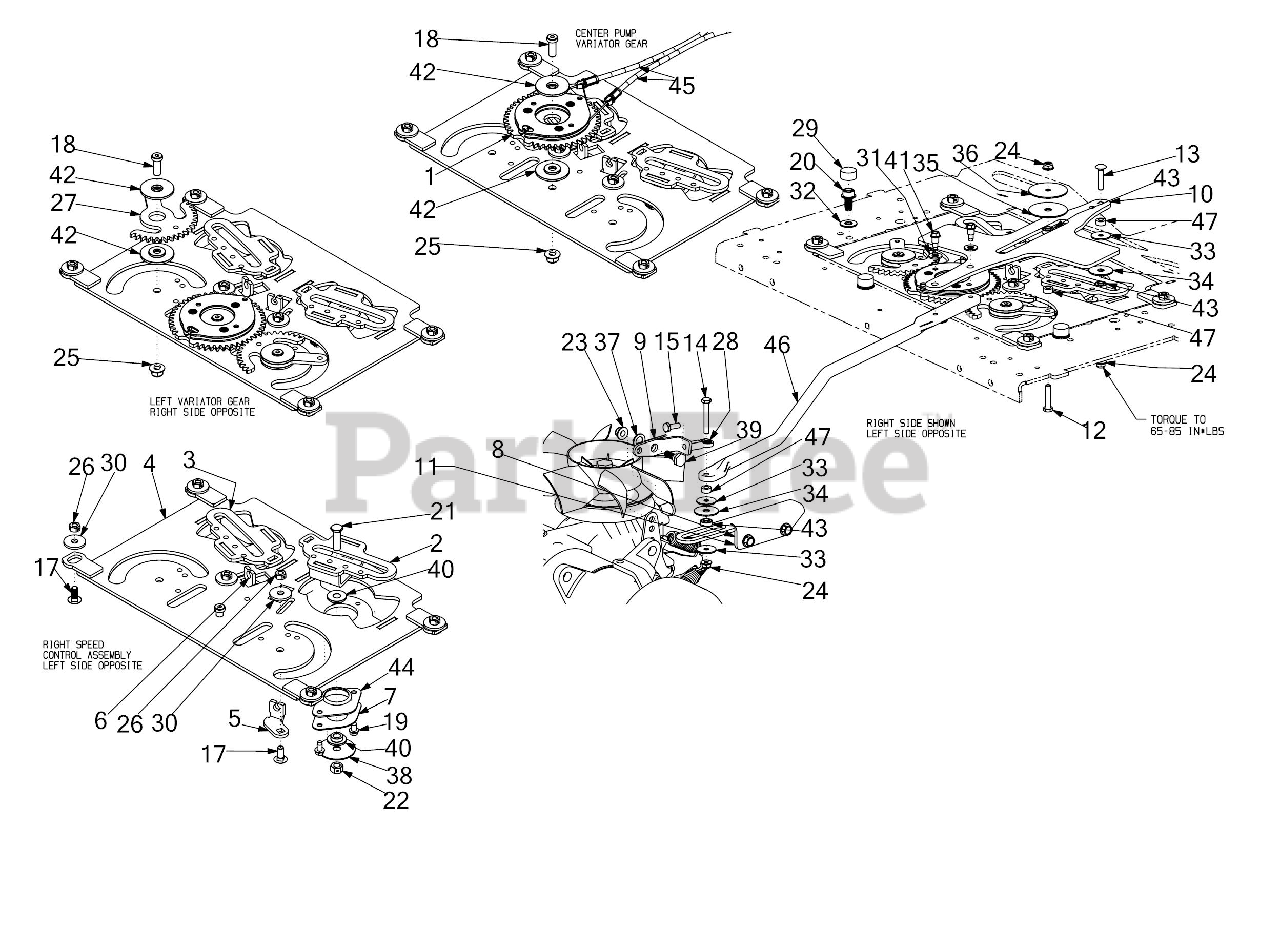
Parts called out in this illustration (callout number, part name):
1	PUMP GEAR
2	PUMP CONTROL CAM ASSEMBLY (RH)
3	PUMP CONTROL CAM ASSEMBLY (LH)
9	PUMP CONTROL BRACKET
10	STEERING PUMP ACTUATOR ARM
12	HEX SCREW 1/4-20 x 1.25
13	CARRIAGE BOLT 1/4-20 x 1.25 Gr5
14	HEX SCREW 1/4-20 x 1.75
15	HEX SCREW 1/4-28 x .75
17	CARRIAGE BOLT 5/16-18 x .75
18	SCREW 3/8-16 x 1
19	SCREW 1/4-20 X.500
20	SCREW 3/8-16 x 3/4
21	SCREW 3/8-16 x 1.25 GR5
23	FLANGE LOCK NUT 5/16-18
24	FLANGE LOCK NUT
26	HEX NUT
27	STEERING GEAR YOKE
28	END ROD (RH)
29	SLIDE CAP
30	FLAT WASHER
31	FLAT WASHER
32	FLAT WASHER
33	FLAT WASHER
34	WASHER .355X1.25X.06THK
35	FLAT WASHER
36	FLAT WASHER
37	FLAT WASHER .469X.750X.054
38	HUB CAP WASHER .406 x 1.92 x .060
39	SHOULDER SCREW .437
40	SHOULDER SPACER
41	SHOULDER SCREW
42	SHOULDER SPACER
43	BALL BEARING .25 x .625 SPCL
44	BALL BEARING
45	TRANSMISSION CONTROL LINK CABLE
46	CONTROL PUMP ROD
